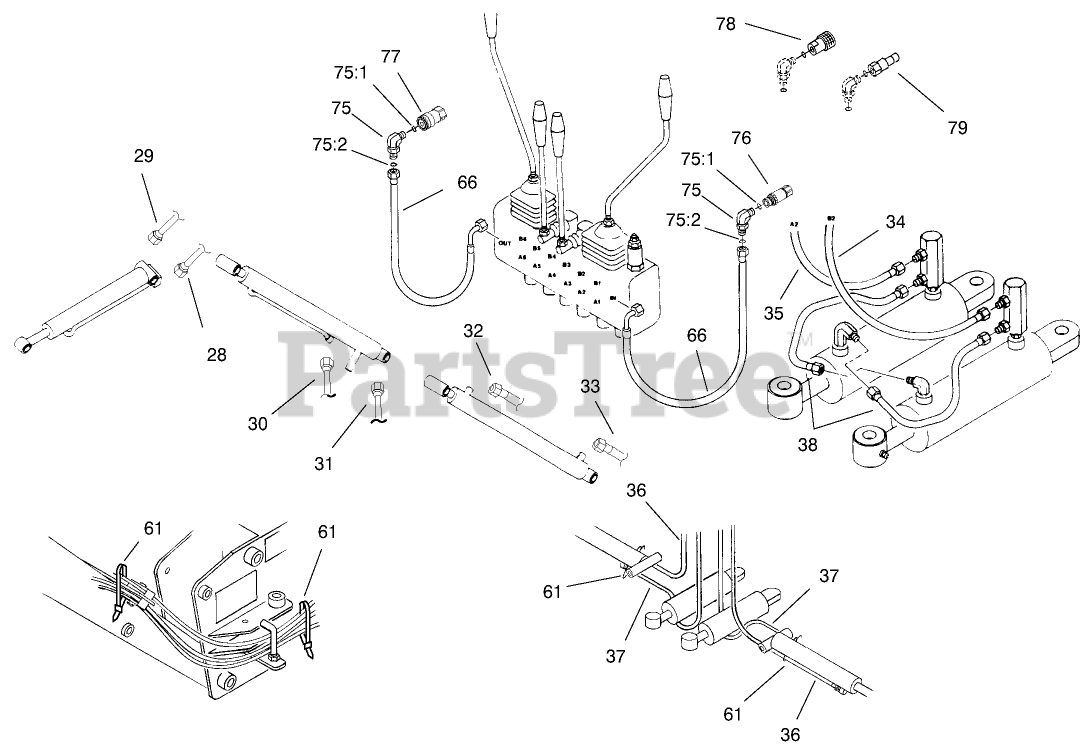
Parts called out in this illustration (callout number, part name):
28	HYD HOSE ASM
29	HYD HOSE ASM
30	HYD HOSE ASM
31	HYD HOSE ASM
32	HYD HOSE ASM
33	HYD HOSE ASM
34	HYD HOSE ASM
35	HYD HOSE ASM
36	HYD HOSE ASM
37	HYD HOSE ASM
38	HYD HOSE ASM
61	TIE-CABLE
66	HOSE-HYDRAULIC
75	FITTING-ELBOW 90
75:1	O-RING
75:2	O-RING
76	NIPPLE-CONNECT, PRESSURE
77	COUPLER-FACE, FLUSH
78	DISCONNECT-QUICK, MALE
79	DISCONNECT-QUICK, FEMALE
